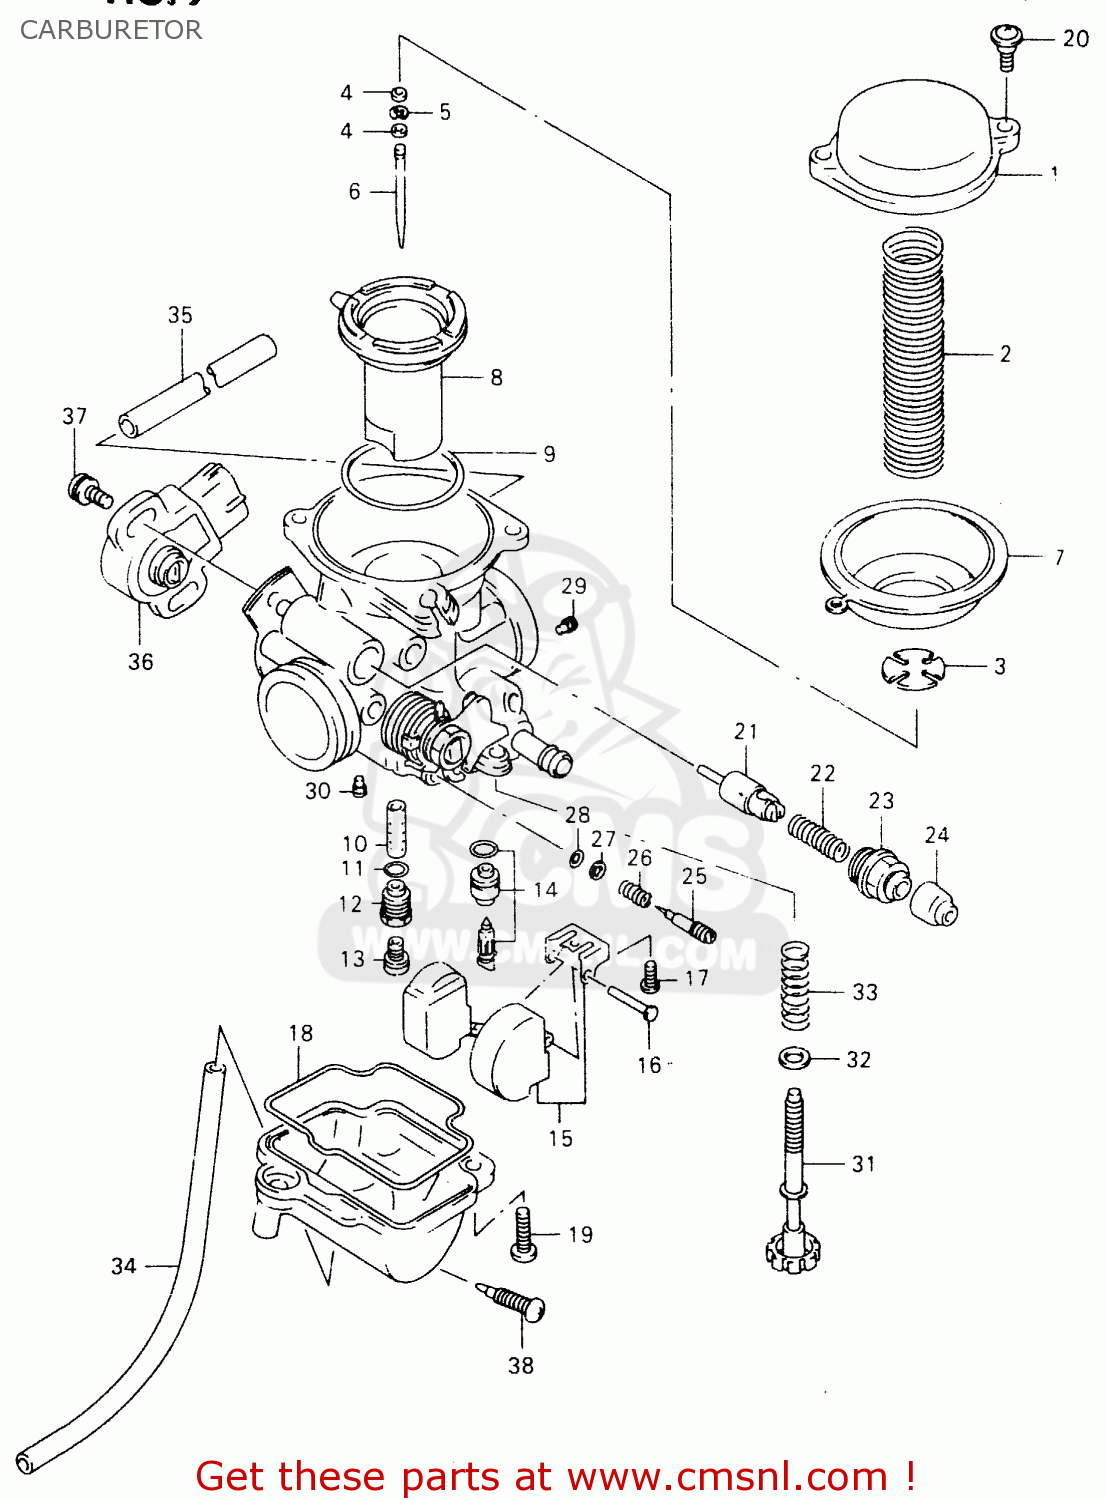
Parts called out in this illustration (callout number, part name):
1	COVER,DIAPHRAGM
2	SPRING
3	PLATE
4	RING
5	E RING,MULTIPLE JET NOZZLE
6	NEEDLE,JET
7	DIAPHRAGM
8	VALVE,PISTON
9	RING
10	JET,NEEDLE(P-0)
11	O RING
12	HOLDER,JET
13	JET,MAIN(110)
14	VALVE ASSY,NEEDLE
15	FLOAT ASSY
16	PIN,FLOAT
17	SCREW
18	GASKET,FLOAT BODY
19	SCREW(5X14)
20	SCREW
21	PLUNGER ASSY
22	SPRING
23	HOLDER,GUIDE
24	CAP
25	ADJUSTER
26	SPRING
27	WASHER
28	O RING,PILOT AIR SCREW
29	JET,PILOT AIR,1.4
30	JET,PILOT(12.5)
31	ADJUSTER
32	WASHER
33	SPRING
34	HOSE(3X5X600)
35	HOSE(4X7X600)
36	SENSOR ASSY,THROTTLE
37	SCREW, SENSOR
38	SCREW,DRAIN
